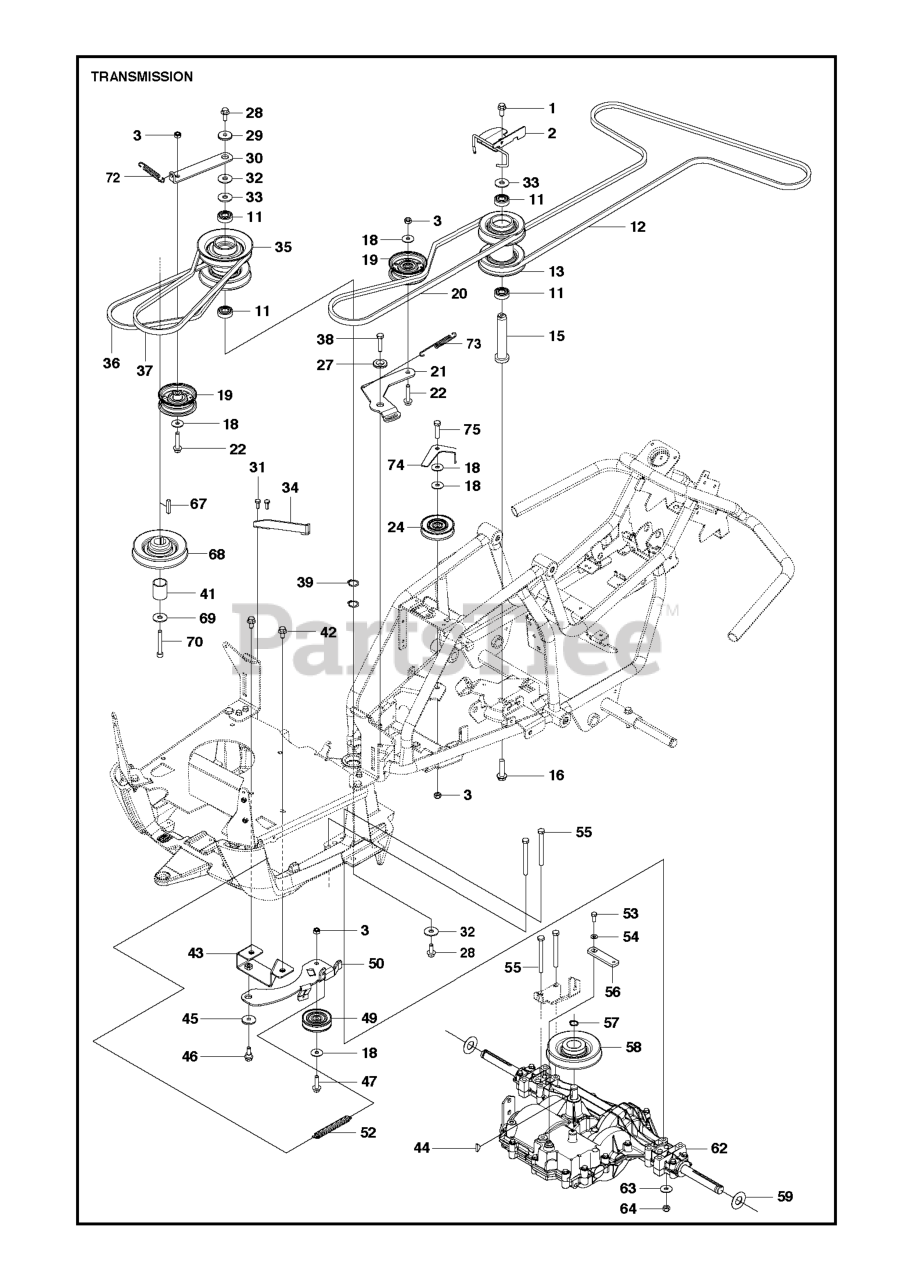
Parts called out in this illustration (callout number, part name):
3	LOCKNUT M8
11	BALL BEARING 6004-2RS1
19	IDLER PULLEY
21	BELT TENSIONER
29	WASHER
31	SCREW
39	RETAINING RING SGA 20
45	WASHER
47	SCREW
54	WASHER
57	Retaining Ring Sga 16
63	WASHER BRB 8.4X17
64	LOCKNUT M8
